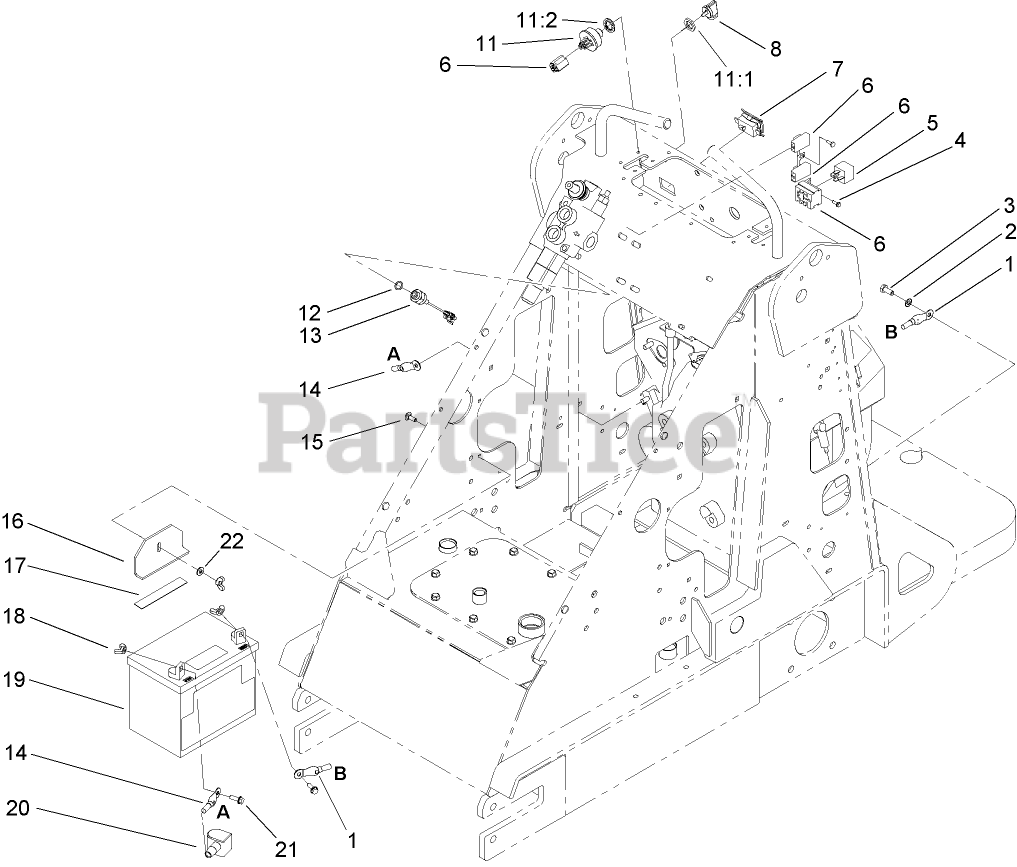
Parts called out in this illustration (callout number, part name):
1	CABLE-BLACK
2	WASHER-LOCK
3	SCREW-HH
4	SCREW-HWHTF
5	RELAY
6	HARNESS-ELECTRICAL
7	METER-HOUR
8	KEY-IGNITION
11	KEY SWITCH ASM
11:2	WASHER-LOCK
12	O-RING
13	SWITCH-BALL
14	WIRE-21 INCH
15	SCREW-CARR
16	CLAMP-BATTERY
17	PAD-FOOTREST
18	NUT-WING
19	BATTERY-DRY
20	BOOT-TERMINAL, RED
21	SCREW-HHF
22	WASHER-FLAT
